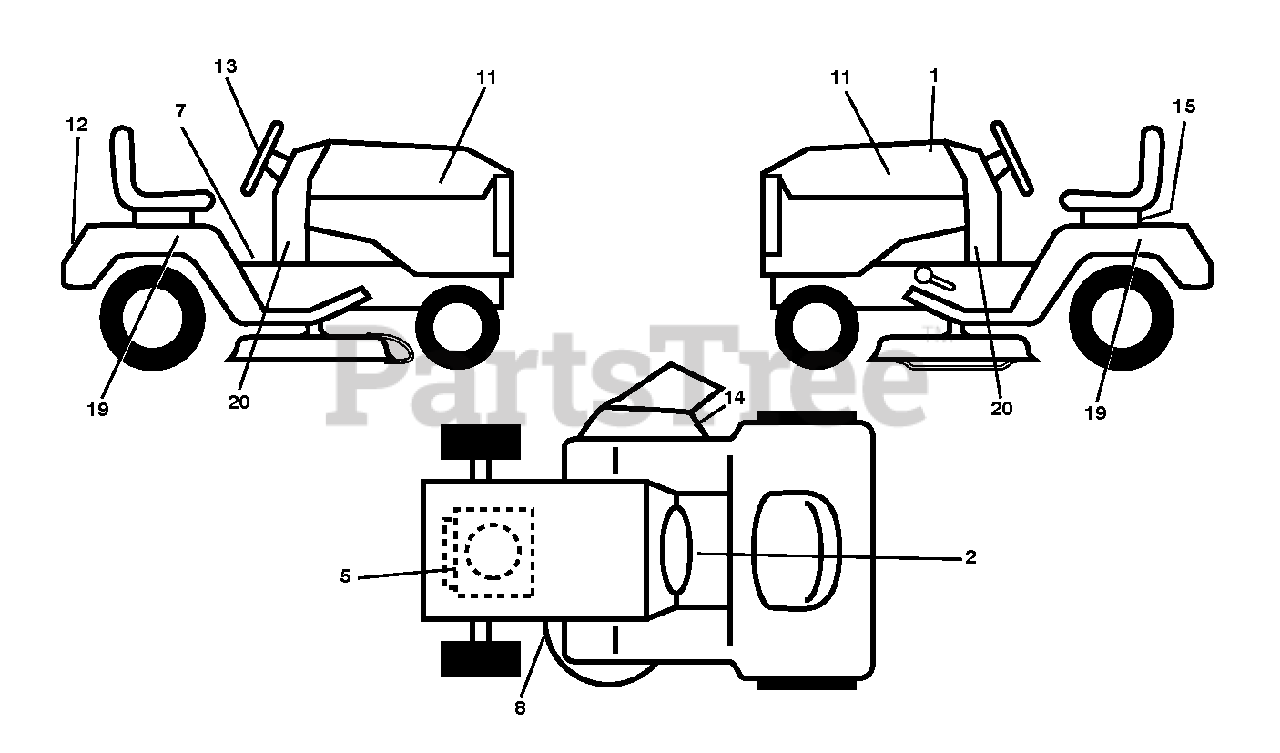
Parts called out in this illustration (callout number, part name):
5	DECAL.ENGINE.BS.14.5.PB.278975
7	Fender Engine Warning Decal
11	DECAL.HOOD.ALPHA.RH/LH.POULAN
12	DECAL.FEND.POULAN.2010
13	DECAL.WHEEL.STRG.STDHRS.POULAN
14	DECAL.WARN.KEEP.HAND.AWAY
15	DECAL BTRY SYMBOLS
19	DECAL.FEND.RH/LH.SET.6S.POULAN
20	DECAL.DASH.LOWER.145/38.11POU
